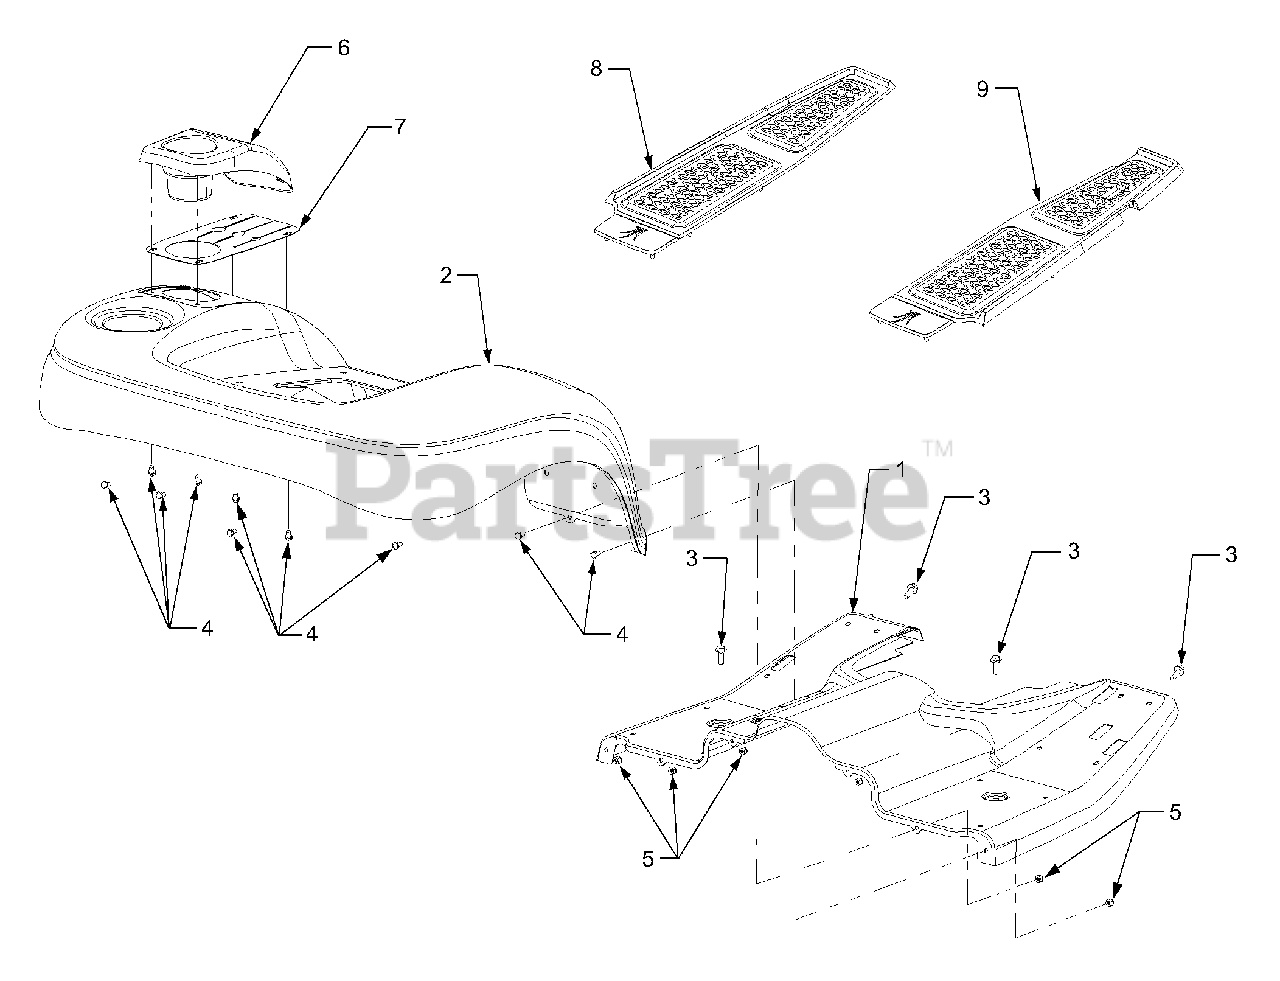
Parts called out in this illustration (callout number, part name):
1	Running Board
2	Fender
3	Screw, Hex Wash. Hd. Tapp 5/16-18 x 1.0
4	Screw, Hex Cap, 1/4-20 x .5 GR5
5	Nut, Hex Lock, 1/4-20
6	Cover, Lift Lever
7	Flap, Lift Lever
8	Pad. Floor LH
9	Pad. Floor RH
